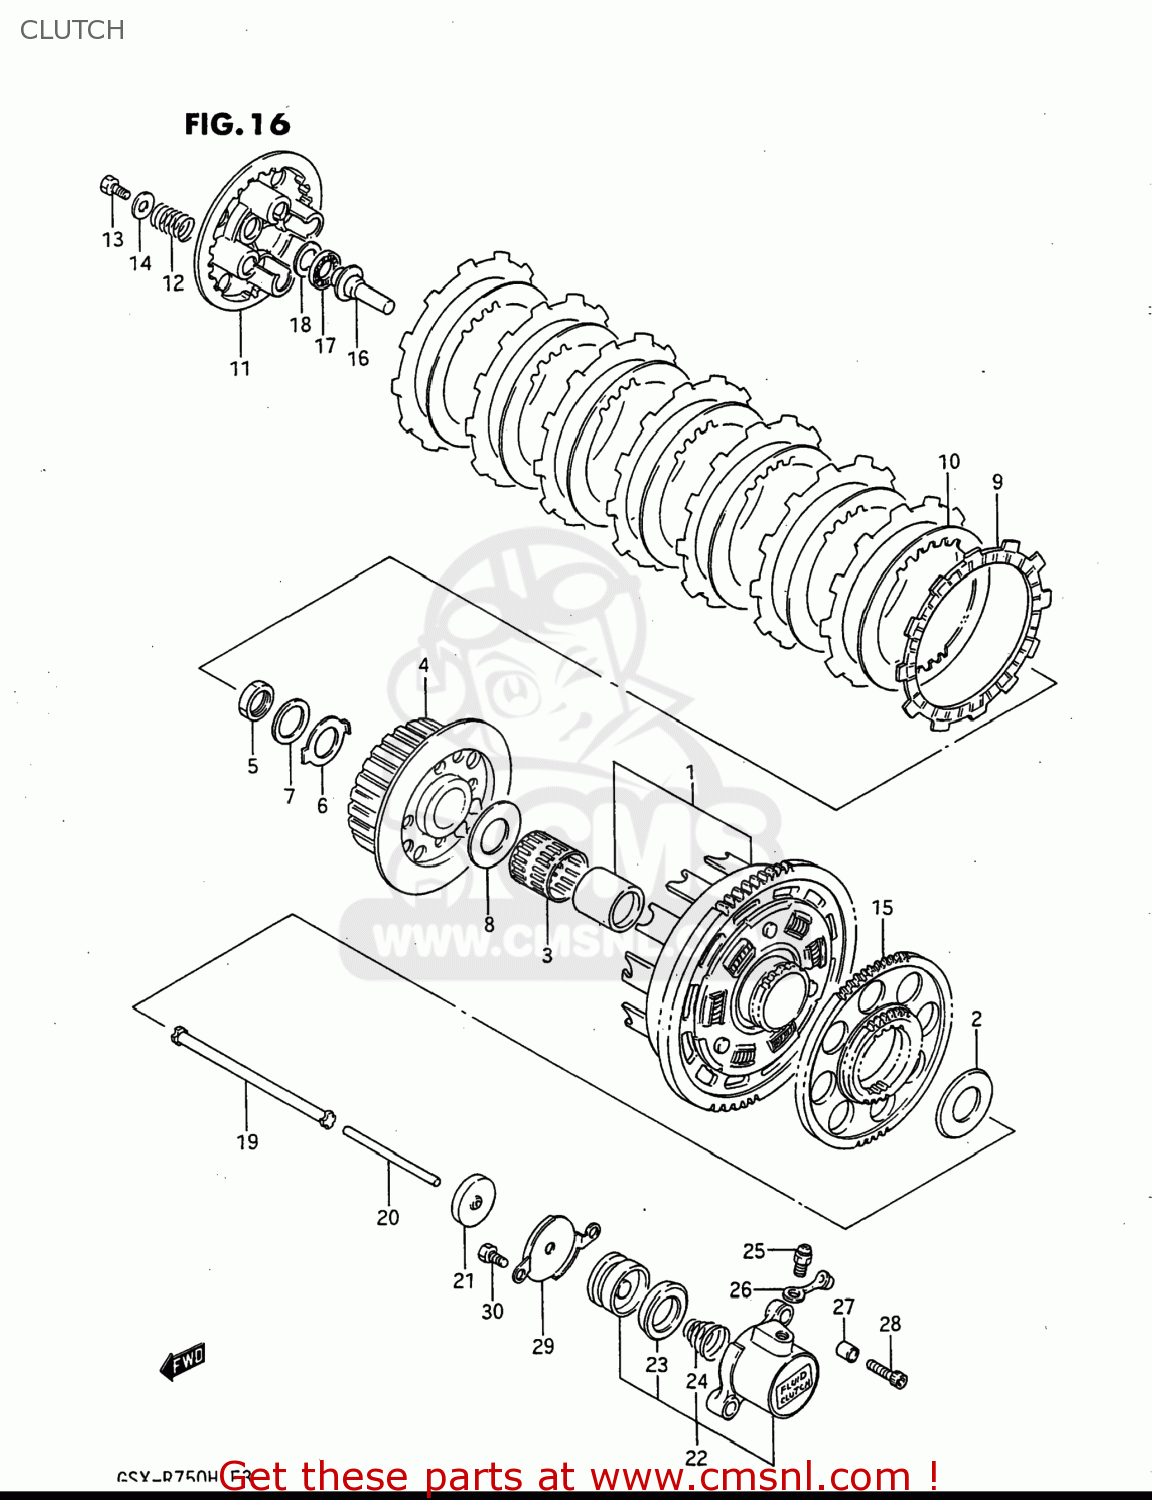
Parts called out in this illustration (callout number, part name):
1	GEAR ASSEMBLY,PRIMARY DRIVE
2	WASHER
3	BEARING(35X40X35.8)
4	HUB,CLUTCH SLEEVE
5	NUT
6	WASHER
7	WASHER
8	WASHER(25X50X2.5)
9	PLATE,CLUTCH DRIVE (NAS)
10	PLATE,CLUTCH DRIVEN (NAS)
11	DISC,CLUTCH PRESSURE
12	SPRING
13	BOLT
14	WASHER
15	GEAR,GENERATOR DRIVE
16	PIECE,CLUTCH PUSH
17	BEARING(15X28X2)
18	WASHER
19	ROD,CLUTCH
20	ROD,CLUTCH PUSH,L
21	SEAL,OIL(6X34X5.5)
22	CYLINDER,CLUTCH RELEASE
23	CUP,CLUTCH CYLINDER
24	SPRING,CLUTCH CYLINDER
25	BLEEDER
26	CAP,BLEEDER
27	PIN
28	BOLT
29	PLATE,CLUTCH PUSH ROD
30	SCREW
